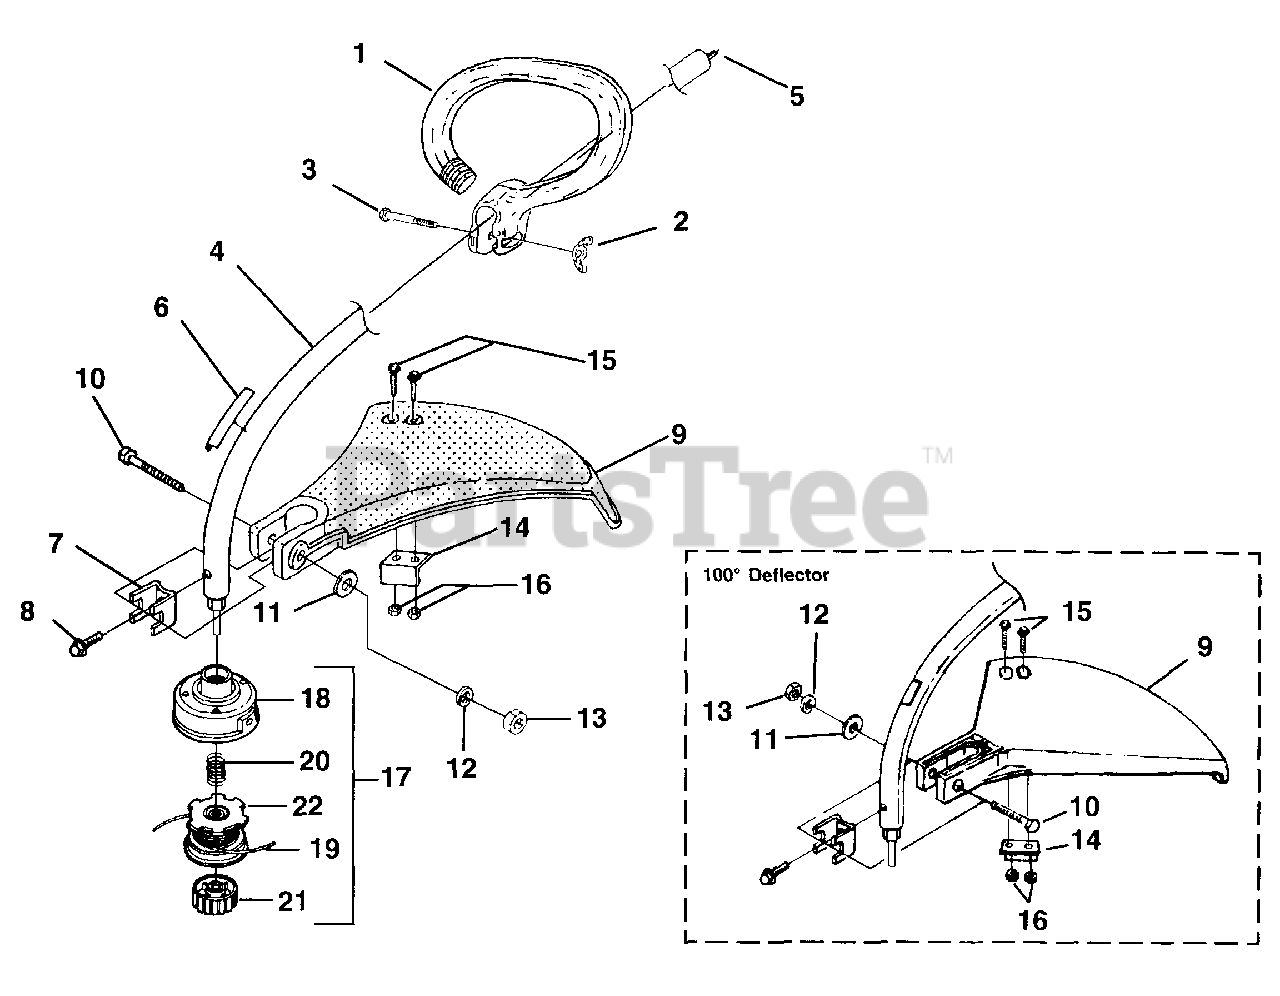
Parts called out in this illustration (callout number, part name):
1	HANDLE ASSY.-Front
2	NUT-Wing, Washer Faced (1/4-20)
3	SCREW-Cap Hex Hd.
4	DRIVESHAFT HOUSING ASSY.
5	SHAFT-Flexible
6	DECAL-Warning
7	CLAMP
8	SCREW-Sems Hex Hd. (#10-24 X 3/8")
9	DEFLECTOR & BLADE KIT (55 Deg.)
10	SCREW-Cap Hex Hd. (10-24 X 2")
11	WASHER-Flat (1/4")
12	WASHER-Lock (1/4")
13	NUT-Hex
14	BLADE-Cut-Off
15	SCREW-Mech. Hex Hd. (10-24 X 7/8")
16	NUT-Hex (10-24)
17	STRINGHEAD-Complete
18	HOUSING & EYELET (Dual Line)
19	SPOOL & STRING (.095" Line)
20	SPRING-Compression
21	RETAINER-Spool (R.H. Thread, Black)
22	STRING - (.095) (113 ft.)
